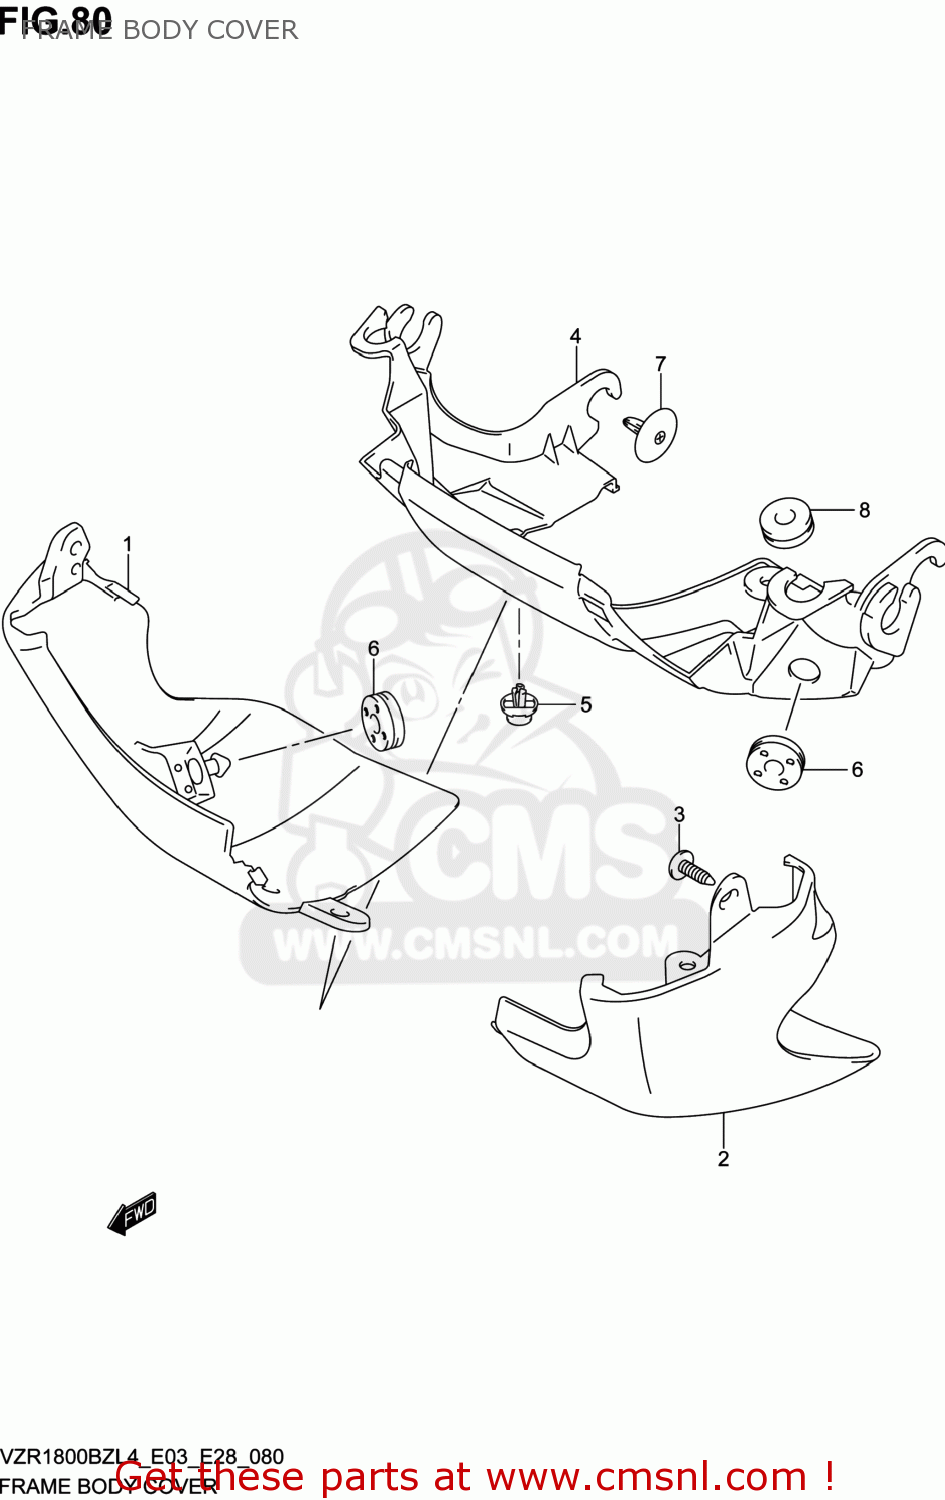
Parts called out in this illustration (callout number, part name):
1	COVER,FRAME BODY,R
2	COVER,FRAME BODY,L
3	SCREW
4	COVER,FRAME BODY LWR
5	CLIP
6	CUSHION
7	PLUG(OD:33)
8	CUSHION
